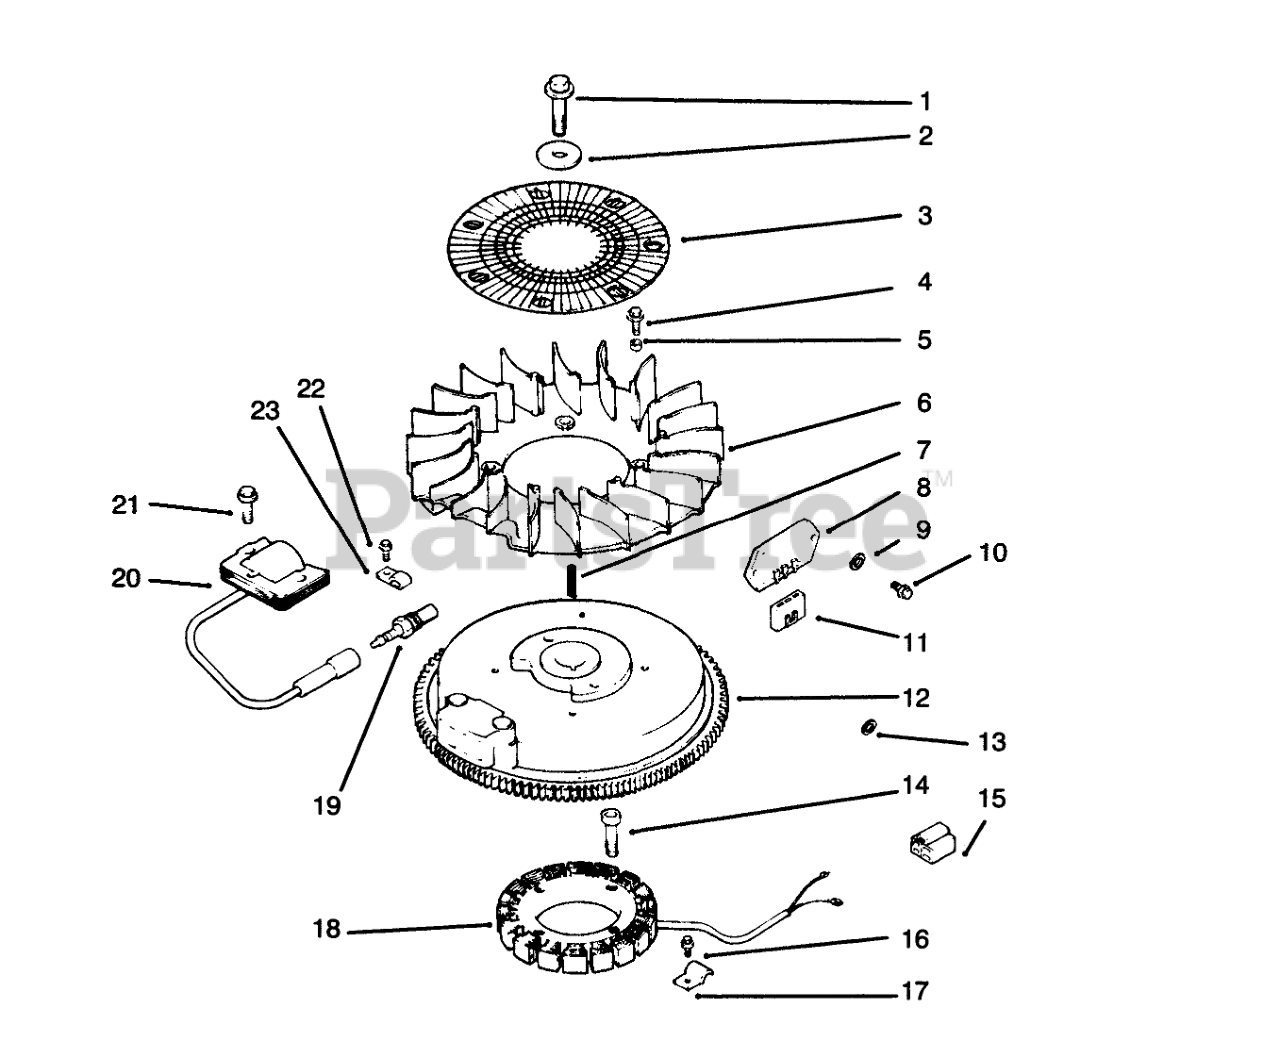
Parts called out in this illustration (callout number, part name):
1	Screw
3	Screen-Grass
4	Screw
5	Spacer-Fan
6	Fan
7	Key
8	Rectifier-Regulator
9	Washer
10	Screw
11	Connector
12	Flywheel ASM
13	Washer
14	Screw
15	Connector
16	Screw
17	Clip
18	Stator-15 amp
19	Spark Plug
20	Module-Ignition
21	Screw
22	Screw
23	Clip
